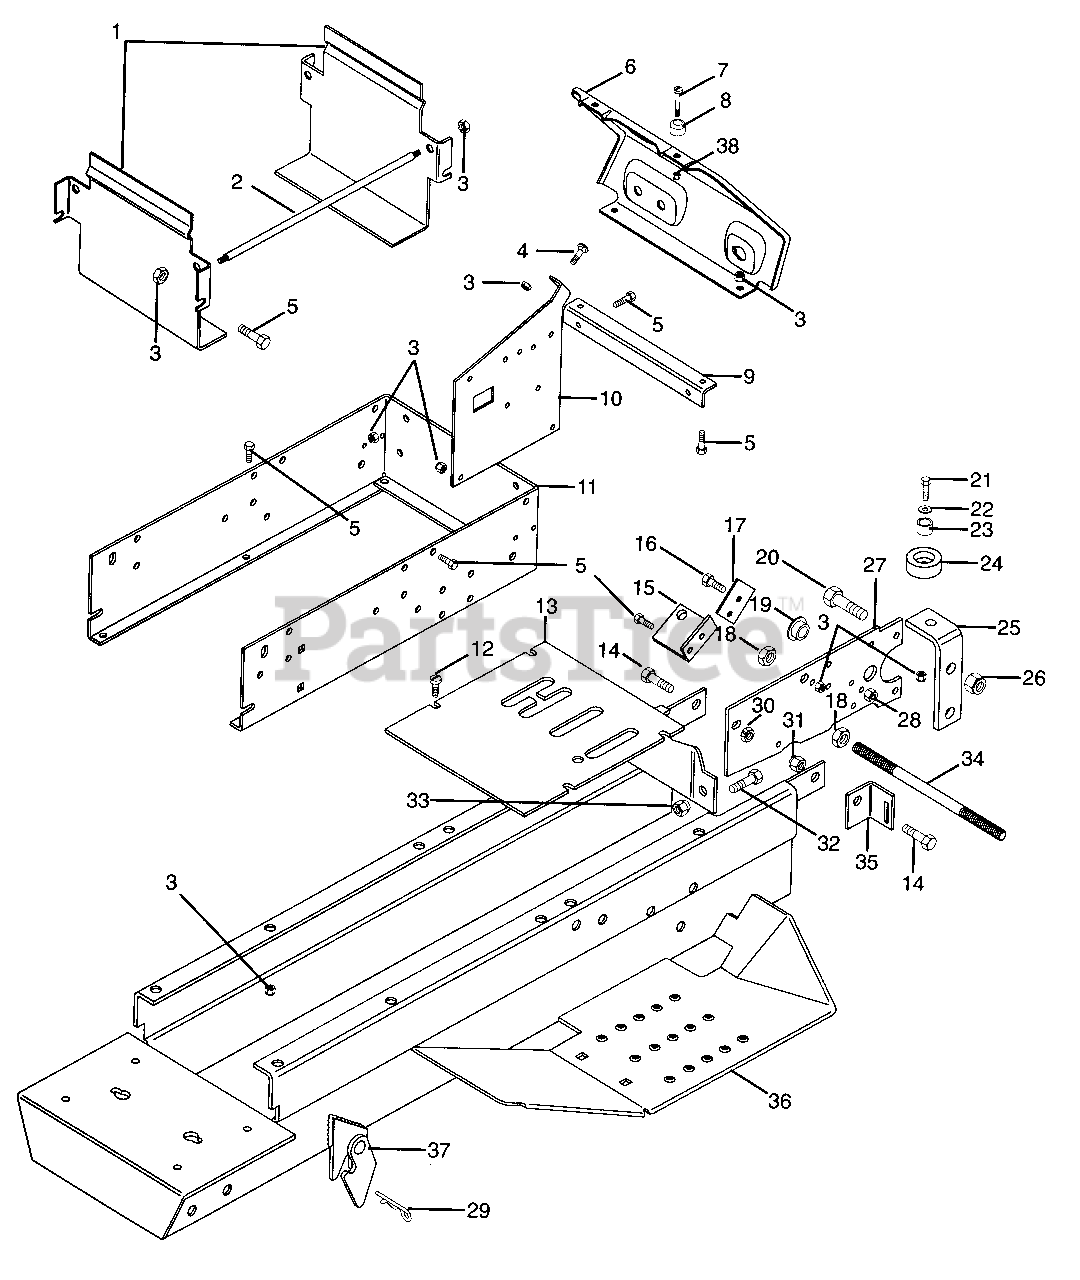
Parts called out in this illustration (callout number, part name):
1	Tank Support
2	Rod-Tank
3	Nut-Locking-Center .250-20 Grade 2
4	Screw-Machine .25-20 x .75
5	Bolt-Hex .25-20 x .75 Grade 5
6	Instrument Panel
6	Decal, G Series Instrument Panel
7	Screw-Machine 6-32 x .75
8	Bumper
9	Bracket-Instrument Panel
10	Bracket-Instrument Panel Left Hand
10	Bracket-Instrument Panel Right Hand
11	Support-Instrument
12	Screw-Tapping .250-20 x .75
13	Plate-Control Cover
13	Decal, G Series Cover Plate (987067-070)
13	Decal, G Series Cover Plate (987066)
14	Bolt-Hex .38-16 x 1.25 Grade 5
15	Bracket-Interlock Switch
16	Bolt-Hex .31-18 x .75 Grade 5
17	Bracket-Bushing Lock
18	Nut-Hex .50-13
19	Bushing-Flange .762 x 1.0 x .580 x 1.48
20	Bolt-Hex .50-13 x 1.50 Grade 5
21	Bolt-Hex .25-20 x 1.25 Grade 5
22	Washer-Flat-Steel .312 x .734 x .065
23	Bushing-Sleeve .265 x .375 x .250
24	Bumper-Seat
25	Bracket-Rear Hitch
26	Nut-Locking-Center .50-13 Grade 5
27	Plate-Forward-Reverse Mounting
28	Nut-Locking-Center .312-18 Grade 2
29	Pin-Hair-Internal .15 x 2.937
30	Nut-Locking-Center .375-16 Grade 2
31	Nut-Locking-Center .375-16 Grade 2
32	Bolt-Hex .50-20 x 1.50
33	Nut-Hex .50-20
34	Rod-Frame External Brace
35	Bracket-Fender Hold-Up
36	Weldment-Frame
37	Weldment-Mower Bracket Right Hand
37	Weldment-Mower Bracket Left Hand
